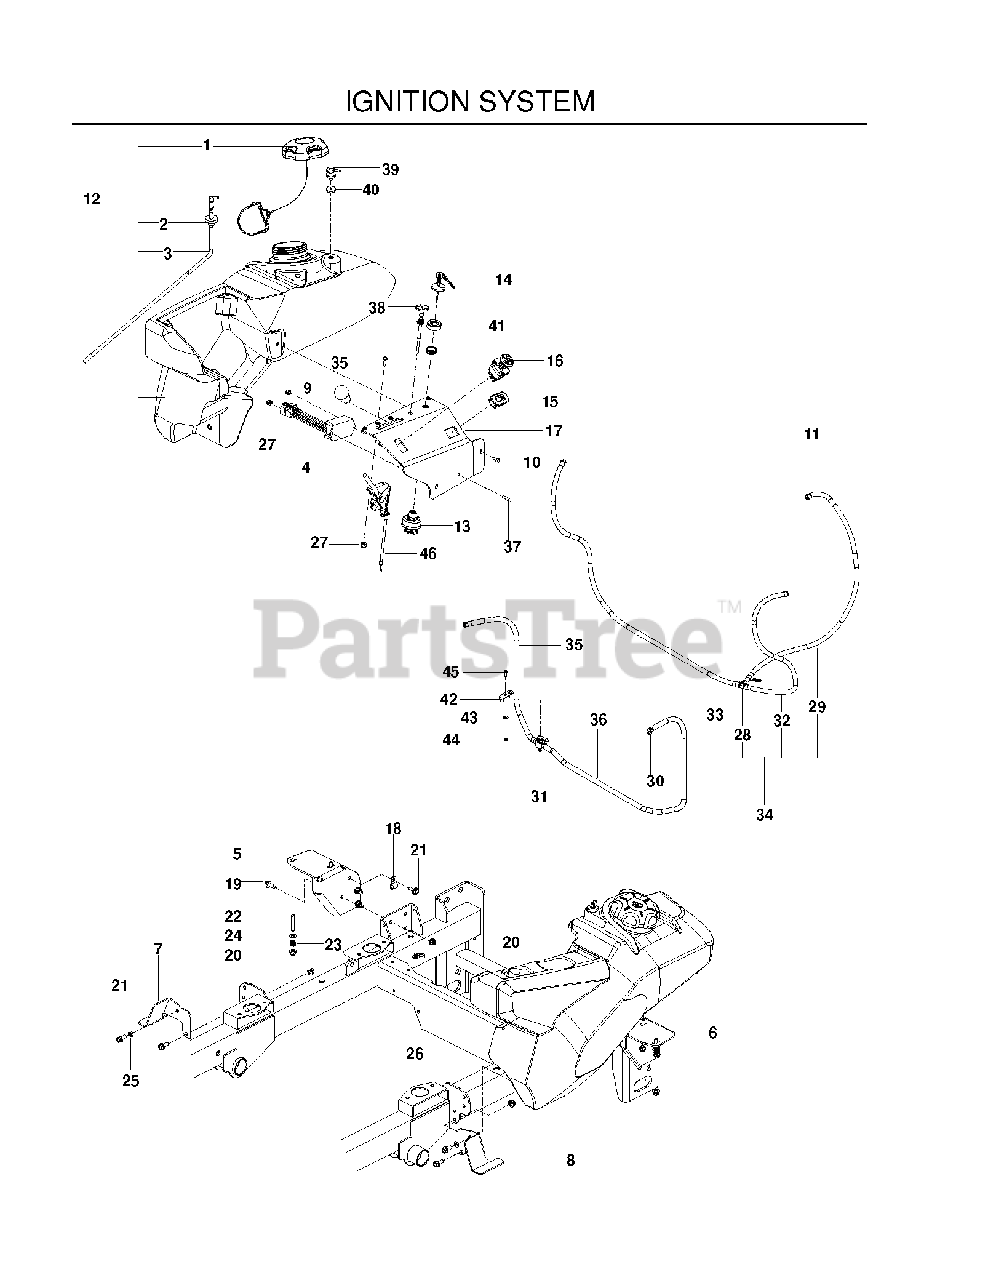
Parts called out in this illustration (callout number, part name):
1	CAP, FUEL
2	RUBBER GROMMET
4	TIMER, SEAT
9	KNOB - SHIFT
10	SCR #10-24 X 3/8 SKT HD BLK OX
11	CLAMP, HOSE
13	SWITCH, IGNITION, INDAK
14	KEY, IGNITION
15	HOUR METER
16	SWITCH, PTO 10 AMP
18	DOUBLE TUBE CLAMP
19	BLT 5/16-18 X 1 THRD FORM ZD
20	5/16-18 NYLOC FLANGE NUT
21	HHFS 5/16-18 X 3/4
22	STUD, 5/16C
24	FLAT WASHER 5/16 SAE
25	WASH 5/16 DISC SPRING ZD
26	TIE WRAP, 8-3/8", W/CLIP
27	NUT 10-24 NYLOC
29	HOSE, VAPOR 3/16 X 30"
30	HOSE CLAMP
31	FUEL VALVE
32	HOSE, 3/16" VAPOR, 21"
33	HOSE, VAPOR 3/16 X 39"
37	SCR #10-24 X .75 SKT HD BLK
38	CABLE, CHOKE, 48"
40	GROMMET, CHECK VALVE
42	BRACKET, VALVE, BLACK
43	WASHER 1/4 FLAT
44	JAM NUT 1/4C
45	HCS 1/4C X 3/4 HCS
46	CABLE, THROTTLE, 46"
